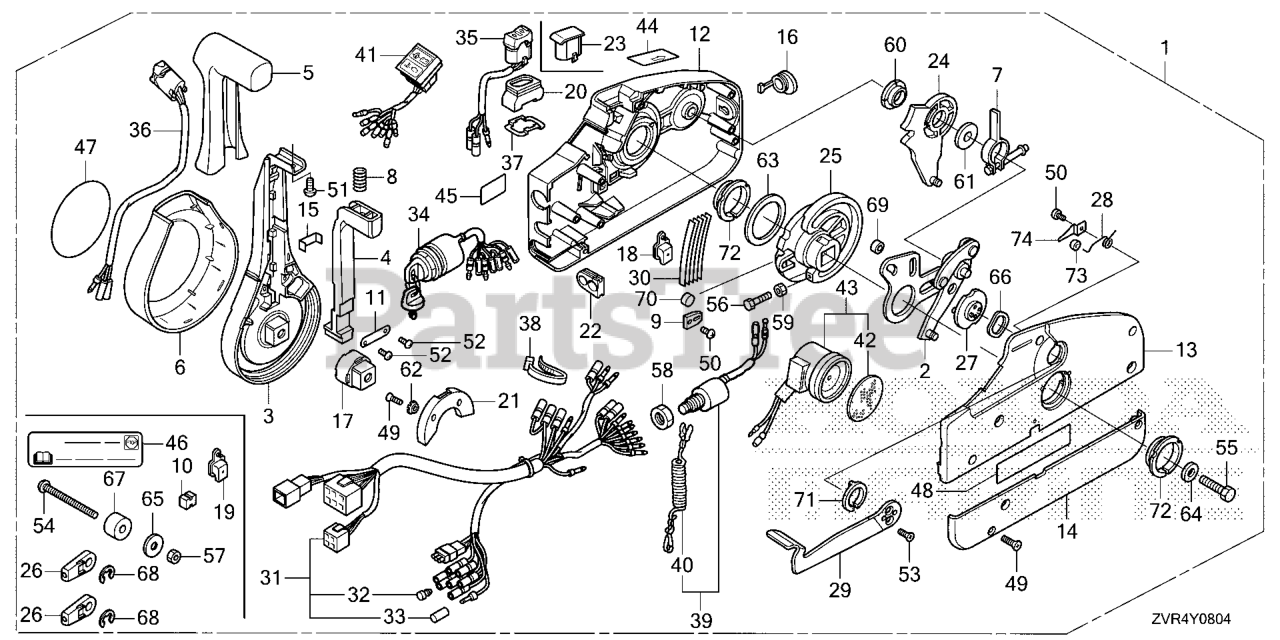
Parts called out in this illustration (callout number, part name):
1	BOX ASSY., REMOTE CONTROL (4-LED) (NHK MEC)
1	BOX ASSY., REMOTE CONTROL (TROLLING CONTROL)(NHK MEC)
2	PLATE ASSY.
3	LEVER, HAND
4	ARM, NEUTRAL LOCK
5	GRIP
6	COVER, LEVER
7	ARM ASSY., BRAKE
8	SPRING (2)
9	CLIP, DETENT
10	SPACER (1) (LOOSE PARTS)
11	BRACKET
12	HOUSING, FR.
13	HOUSING, RR.
14	PANEL, BACK
15	BRACKET, WIRE CLAMP
16	CAP, RUBBER
17	ADJUSTER
18	COVER, POWER TRIM-TILT WIRE (LOOSE PARTS)
19	COVER, POWER TRIM-TILT WIRE (LOOSE PARTS)
20	SEAL, RUBBER
21	HOLDER, NEUTRAL LOCK
22	GROMMET, WIRE (14)
23	CAP, TROLLING CONTROL SWITCH BLANK
24	GEAR ASSY., SHIFT
25	GEAR, DRIVE
26	TERMINAL, CABLE (LOOSE PARTS)
27	DRUM ASSY., FREE THROTTLE
28	SPRING (1)
29	LEVER, FREE THROTTLE
30	SPRING, DETENT
31	CABLE ASSY., REMOTE CONTROL (B)
31	CABLE ASSY., REMOTE CONTROL (B)(TROLLING CONTROL)
32	PLUG, CONNECTOR (INNER) (TROLLING CONTROL)
33	PLUG, CONNECTOR (OUTER) (ENGINE NO.)
34	SWITCH ASSY., COMBINATION (SINGLE) (DUAL)
35	SWITCH ASSY., TROLLING CONTROL
36	SWITCH ASSY., POWER TRIM-TILT
37	PLATE, SWITCH
38	BAND, WIRE
39	SWITCH ASSY., EMERGENCY STOP
40	WIRE, EMERGENCY (SINGLE) (DUAL)
41	LAMP ASSY., INDICATION
42	PLATE, TURN SIGNAL BUZZER DUAL QTY = (2) (SINGLE)
43	BUZZER, WARNING DUAL QTY = (2) (SINGLE)
44	MARK, FAST IDLE
45	MARK, EMERGENCY STOP (US) (LOOSE PARTS)
46	MARK, EMERGENCY STOP (US) (LOOSE PARTS)
47	MARK, EMBLEM
48	LABEL, SIGP
49	SCREW (5X18)
50	SCREW (4X6)
51	SCREW (5X10)
52	SCREW (4X10)
53	SCREW (5X12)
54	SCREW (6X90) (LOOSE PARTS)
55	BOLT (8X50)
56	BOLT (5X25)
57	NUT (6MM) (LOOSE PARTS)
58	NUT, HEX. (16MM) DUAL QTY = (2) (SINGLE)
59	NUT (5MM)
60	BEARING (1)
61	WASHER (3)
62	WASHER (4)
63	WASHER (5)
64	WASHER (8MM)
65	WASHER (7) (LOOSE PARTS)
66	WASHER, WAVE
67	SPACER (2) (LOOSE PARTS)
68	E-RING (6MM) (LOOSE PARTS)
69	ROLLER, DRIVE GEAR CAM
70	ROLLER
71	BEARING (2)
72	BEARING (3)
73	ROLLER, FREE THROTTLE
74	CLIP, ROLLER
